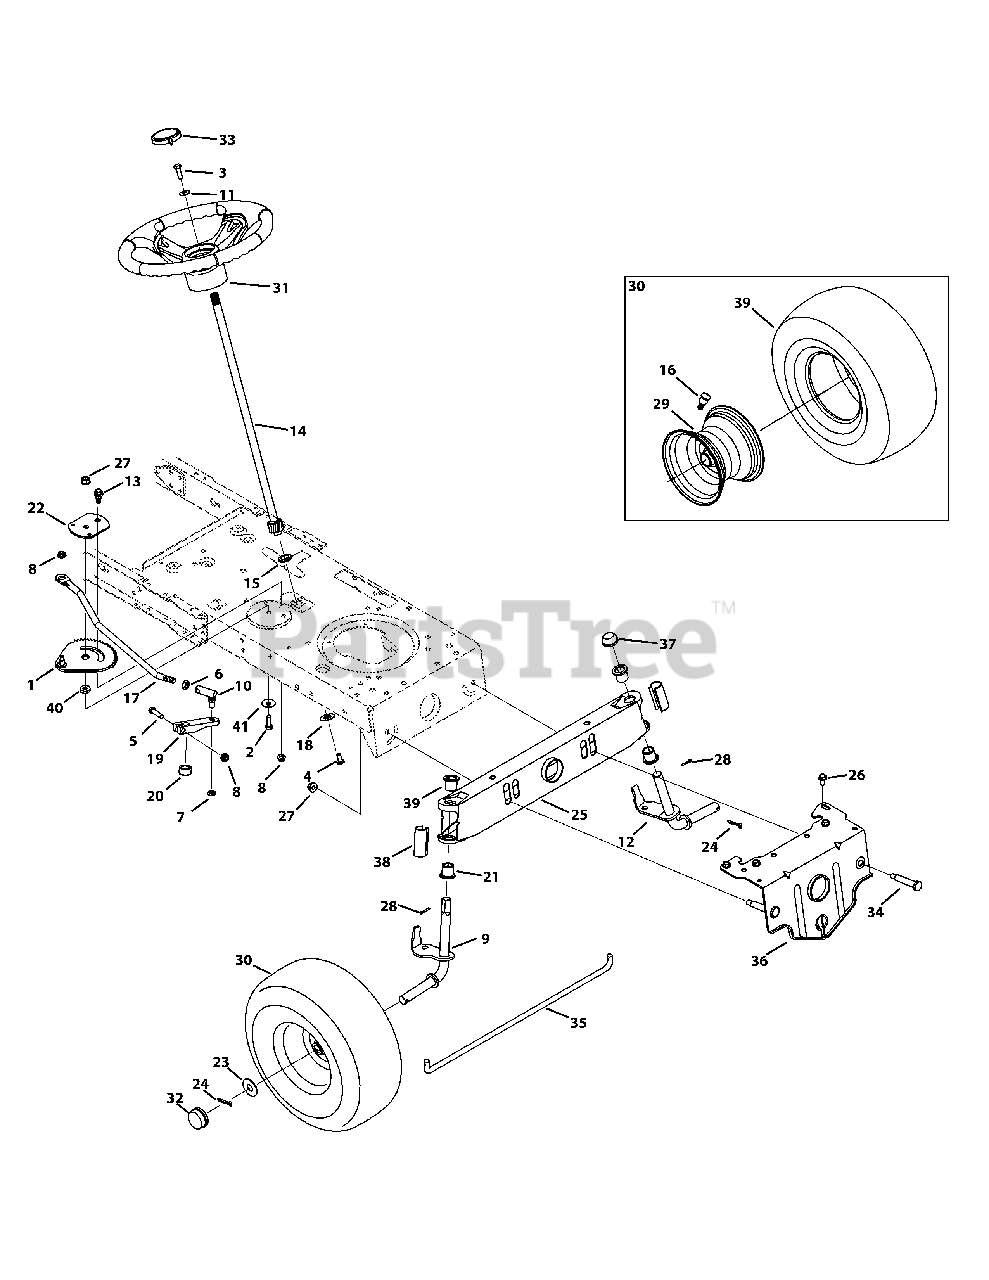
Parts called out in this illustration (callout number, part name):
1	Front Steering Gear Assembly
2	Hex Screw, 3/8-16 x 1.00
3	Hex Screw, 5/16-18 x 1.00, Lock
4	Machine Screw, 5/16-18 x .750
5	Hex Screw, 5/16-18 x 1.75
6	Jam Nut, 7/16-20
7	Jamlock Nut, 3/8-24
8	Flangelock Nut, 5/16-18
9	42" & 46" Front RH Axle
10	Ball Joint, 7/16-20
11	Bell Washer, .340 x .872 x .060
12	42" & 46" Front LH Axle
13	Shoulder Bolt, 5/16-18 x .435 x .350
14	Steering Shaft, 5/8
15	Flange Bearing, 5/8
16	Valve, tubeless Air
17	Steering Link
18	Cap, 1.25 x .16
19	Steering Block
20	Spacer, .71 x .125 x .56
21	Flange Bearing, .760 x .941 x 1.0
22	Stabilizer Plate
23	Flat Washer, .781 x 1.590
24	Cotter Pin, 5/32 x 1.25
25	Pivot Axle
26	Screw, 5/16-18 x .750
27	Flangelock Nut, 3/8-16
28	Cotter Pin, .125 x .75
29	Rim Asm, 6.0 x 4.5
30	Wheel Ass’y, Sq. Shldr., 15 x 6 x 6
31	Steering Wheel
32	Hub Cap
33	No Sprig Cap
34	Shoulder Bolt, 3/8-16 x .500 x 2.38
35	Fixed Rod
36	Pivot Bar Bracket
37	Push Cap, 3/4
38	Standard Axle Cap
39	Tire, 15 X 6 X 6 Sq Shoulder
40	Spacer, .38 ID x .854 OD x .20
41	Bell Washer, .390 x 1.13 x .062
